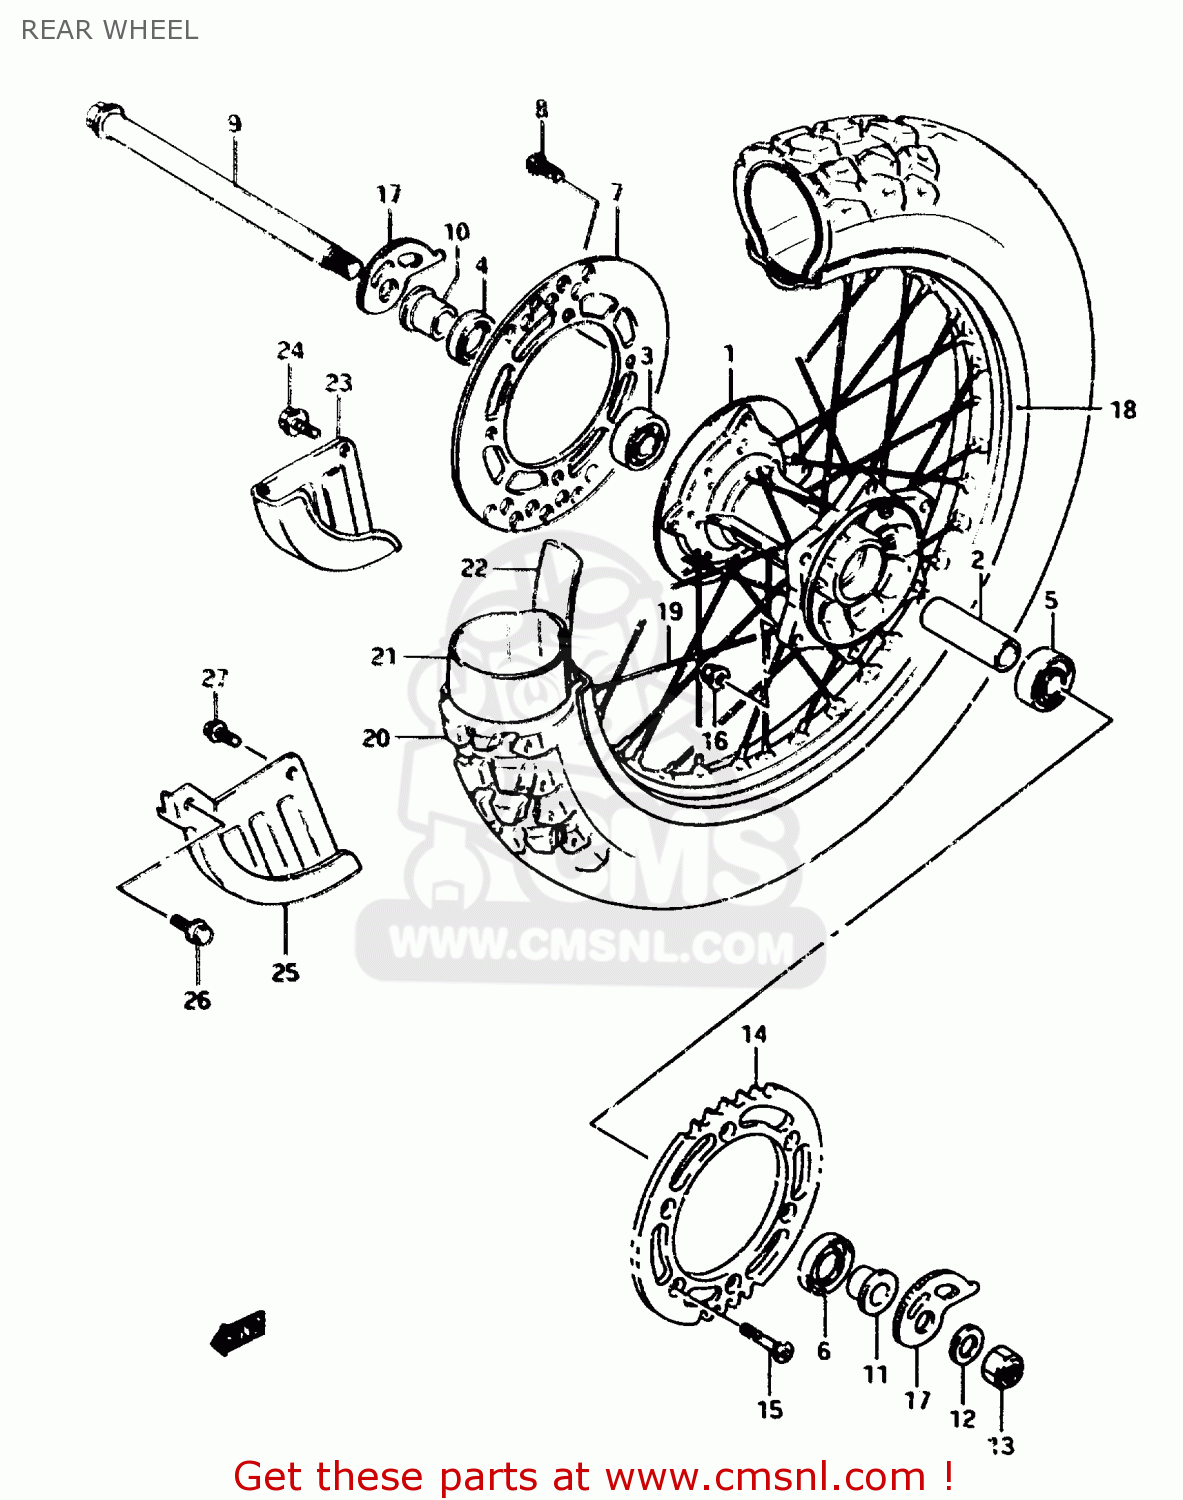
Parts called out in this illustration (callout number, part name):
1	HUB, REAR
2	SPACER(17.3X24X112)
3	BEARING
4	SEAL,OIL(26X42X8)
5	BEARING
6	OIL SEAL
7	DISC,RR BRAKE
8	BOLT
9	AXLE,RR
10	SPACER, RH
11	SPACER, LH
12	WASHER(17X30X3)
13	NUT 16MM
14	SPROCKET, REAR (NT:50)
15	SCREW(8X33.5)
16	NUT
17	ADJUSTER,CHAIN
18	RIM, WHEEL (1.85X18)
19	SPOKE SET,RR WHEEL
20	TIRE, REAR (4.10-18)
21	TUBE ASSEMBLY,WHEEL,INNER
22	PROTECTOR,INNER TUBE
23	COVER,REAR DISC
24	BOLT
25	COVER,REAR DISC
26	BOLT 6X20
27	BOLT
